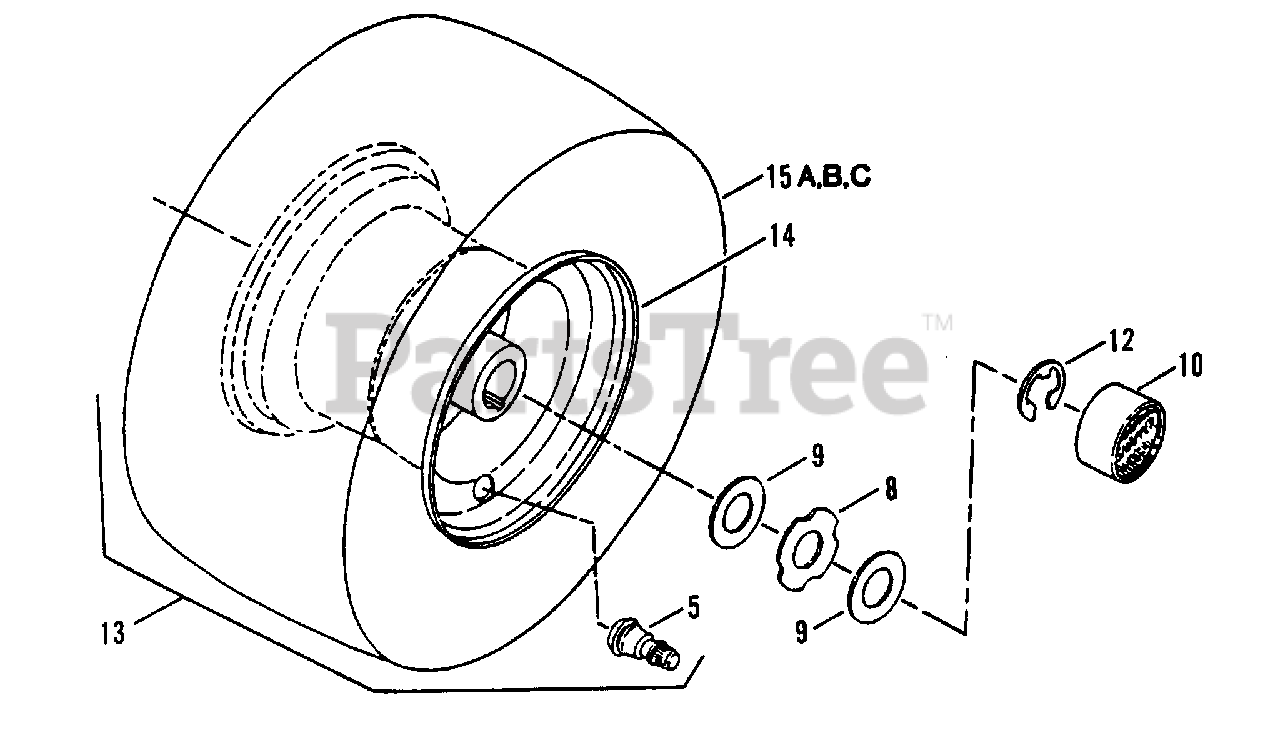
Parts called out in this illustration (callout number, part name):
5	VALVE, Air (Snap-In)
8	WASHER, Hub-Cap Retaining
9	WASHER, Flat, 1/16 x 49/64 1.9. x 1-5/16" O.D.
10	HUB-CAP
12	RING,External Retaining, 3/4"
13	ASSEMBLY, Rear Tire & Rim
14	RIM, 8 x 7.00
15A	TIRE, 18 x 8.50
15B	TIRE, 18 x 9.50
15C	TIRE, 20 x 10.00
